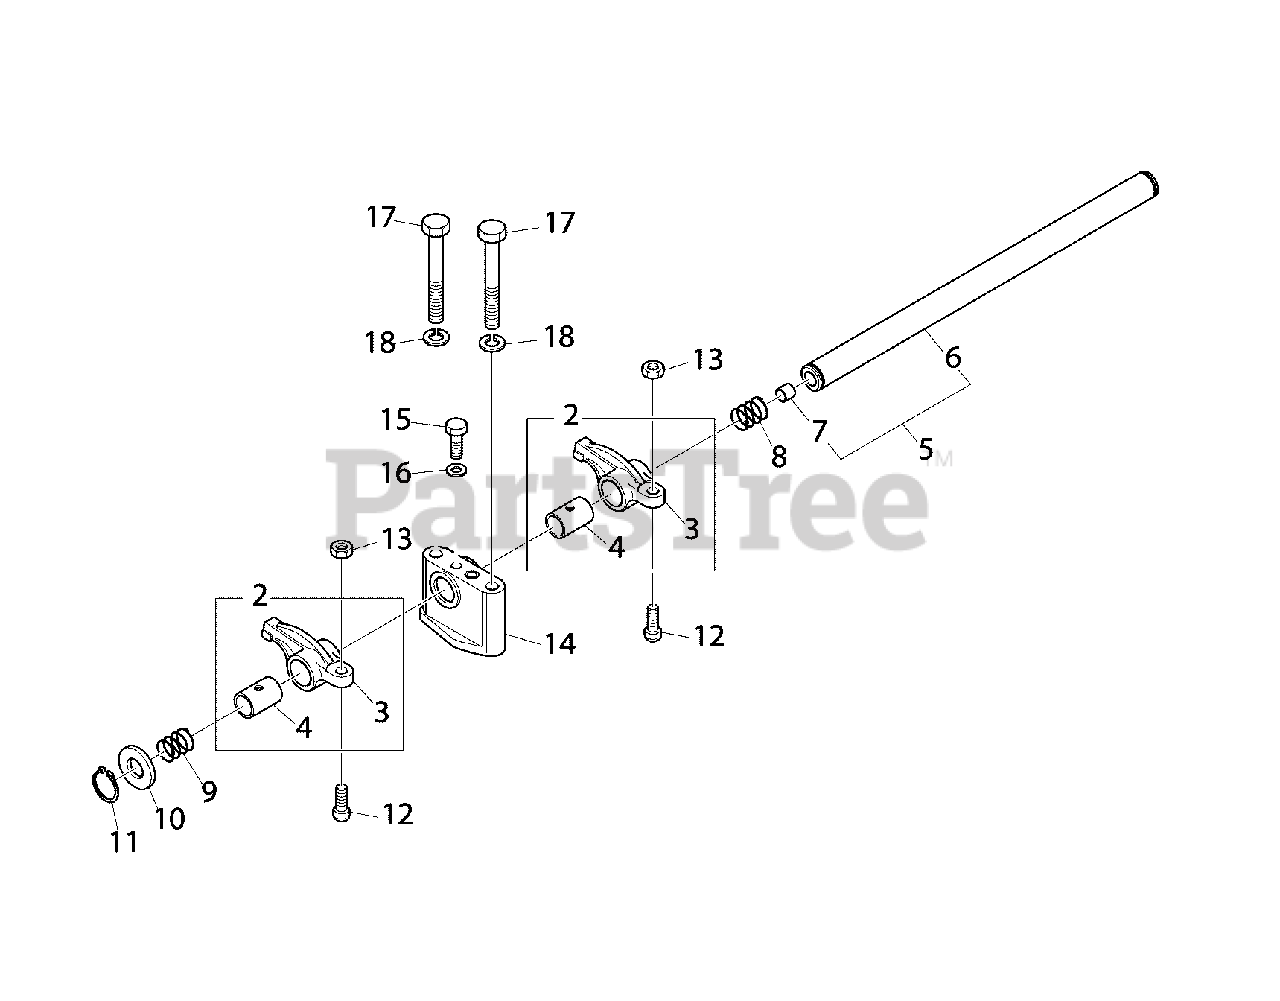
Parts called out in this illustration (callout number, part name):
1	* SHAFT, ROCKER ARM ASSEMBLY
2	* ARM, ROCKER ASSEMBLY
3	* ROCKER ARM
4	* BUSHING
5	* SHAFT, ROCKER ARM
6	* SHAFT, ROCKER ARM
7	* PLUG, CORE
8	* SPRING, COMPRESS
9	* SPRING, COMPRESS
10	* WASHER
11	* RING, SNAP
12	* SCREW, ADJUST
13	* NUT, HEX
14	* BRACKET, ROCKER ARM
15	* BOLT
16	* WASHER
17	* BOLT, HEX
18	* WASHER, SPRING
